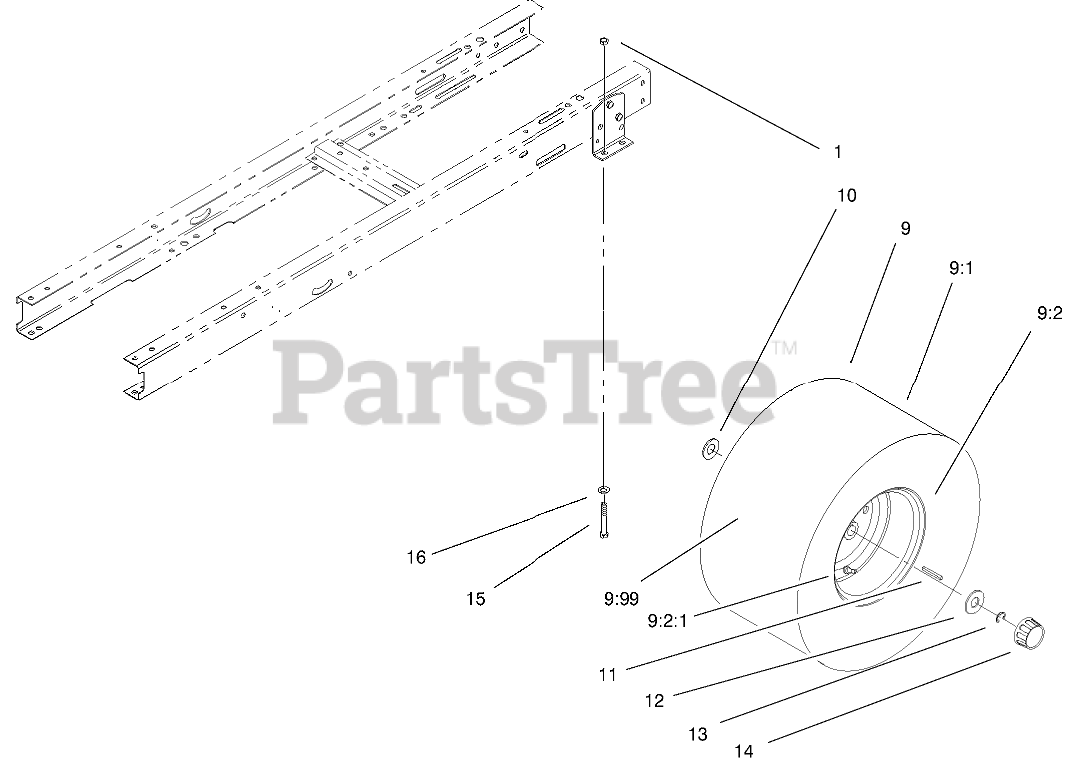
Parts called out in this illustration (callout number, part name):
1	NUT-LOCK, NI
9	Wheel&tire ASM,Rear
9:1	TIRE
9:2:1	STEM-VALVE
9:99	Tube
10	WASHER-THRUST
11	KEY-SQUARE
12	WASHER-PLAIN
13	E-RING
14	CAP-HUB
15	SCREW-HH
16	WASHER-PLAIN
